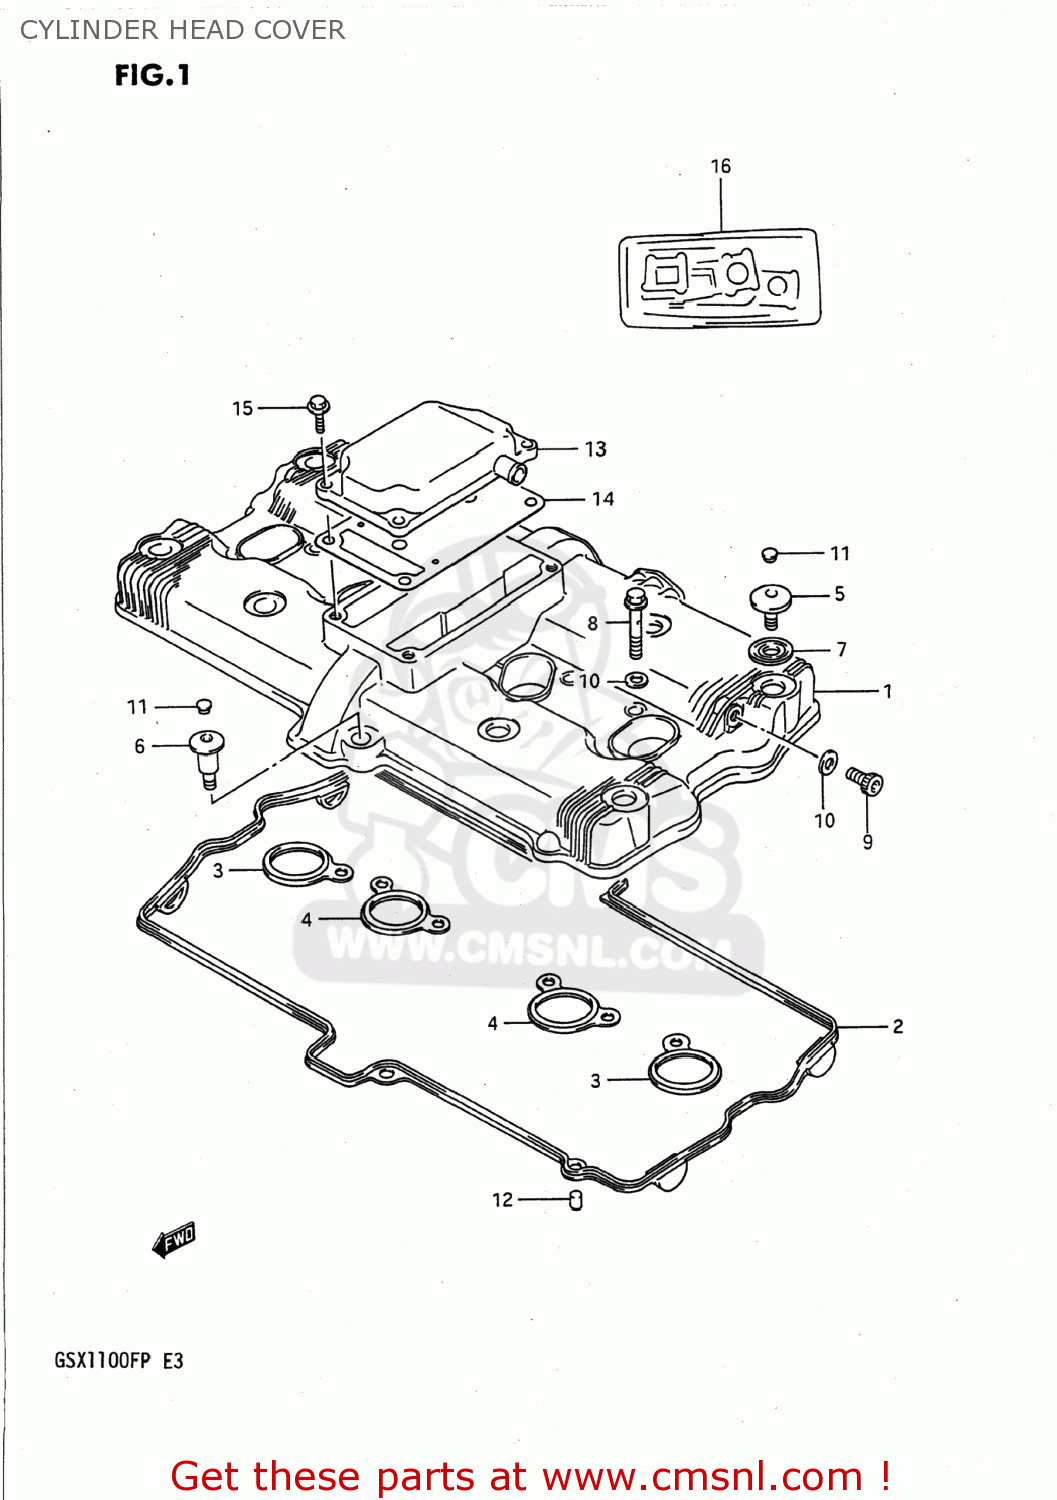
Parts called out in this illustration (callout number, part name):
1	COVER,CYLINDER HEAD
2	GASKET,CYLINDER HEAD COVER (NAS)
3	GASKET,HEAD COVER NO.2 (NAS)
4	GASKET,HEAD COVER NO.3 (NAS)
5	BOLT(7X17.5)
6	BOLT(7X31)
7	WASHER
8	BOLT,UNION 8X35
9	PLUG, HEAD COVER
10	GASKET 8.2X14X1 (NAS)
11	CAP(OD:10)
12	PIN
13	COVER,BREATHER
14	GASKET (NAS)
15	BOLT
16	GASKET SET (NAS)
